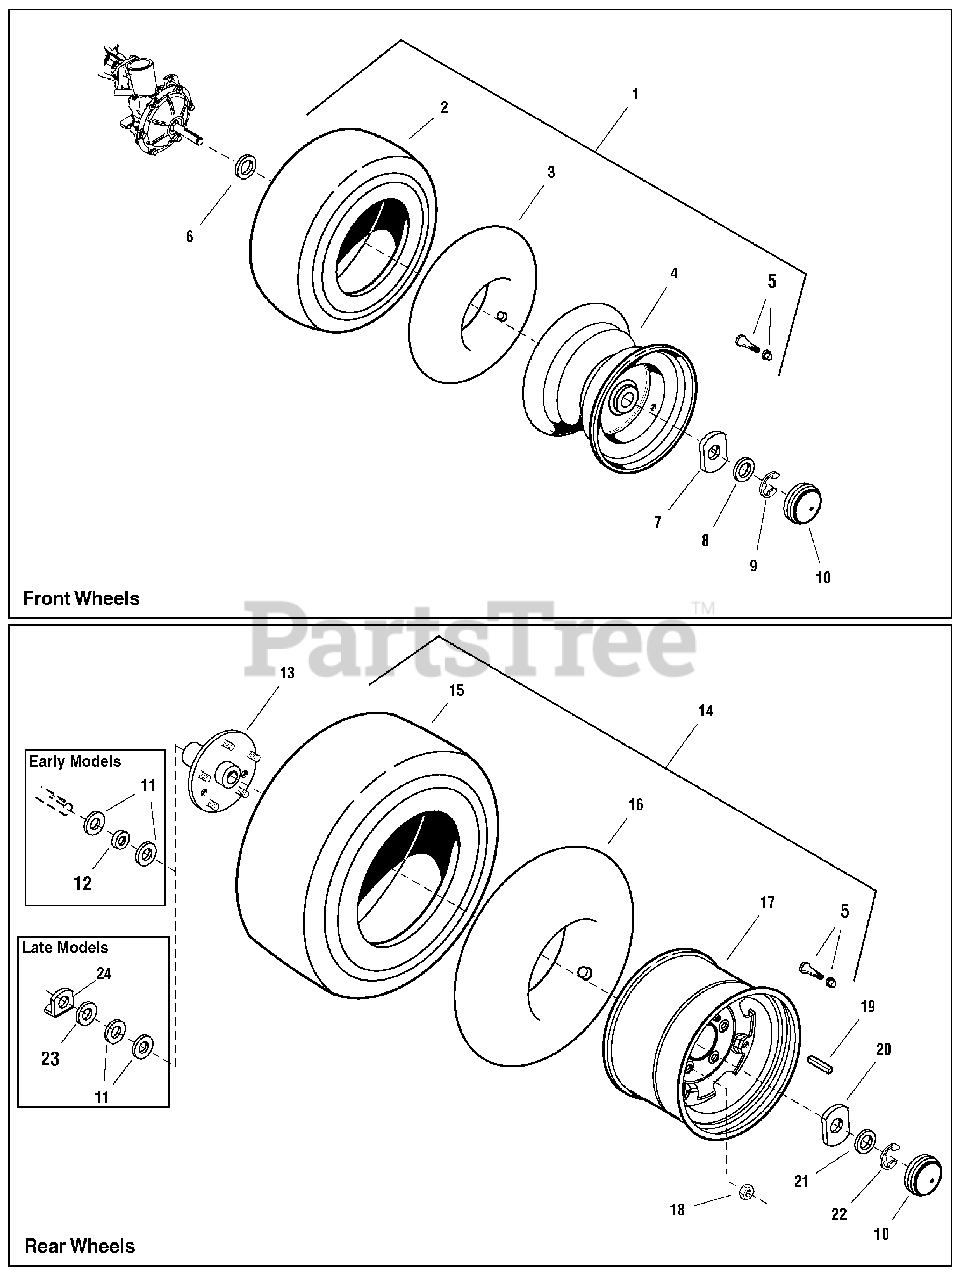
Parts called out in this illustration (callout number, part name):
1	WHEEL & TIRE ASSEMBLY
2	TIRE, 16 x 6-1/2-8
4	WHEEL ASSEMBLY
5	VALVE STEM & CAP
6	WASHER, Flat 3/4 x 1-5/8 x 1/8
7	WASHER, Flat
8	WASHER, 3/4
11	WASHER, 1 x 2-1/4 x 1/8
12	SPACER
13	PLATE & HUB WELDMENT
14	WHEEL & TIRE ASSEMBLY
15	TIRE, 23 x 10-1/2-12
18	NUT, Hex 7/16-20 For Wheel Bolt
19	KEY, Hi-Pro 1/4 x 2
20	WASHER, Flat
21	WASHER, Flat
23	WASHER, Flat, 1"
24	BRACKET, Washer Axle
